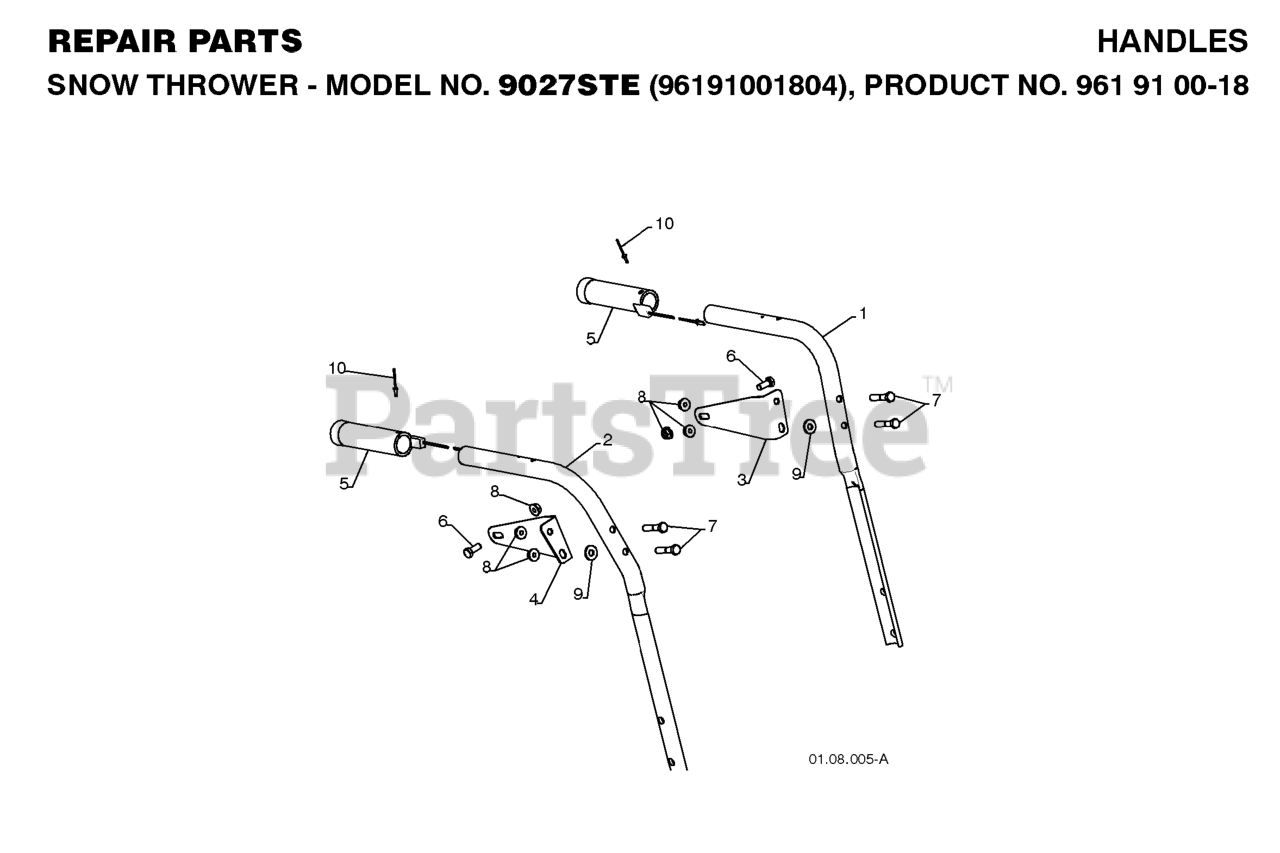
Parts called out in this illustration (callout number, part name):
1	TUBE.HANDLE.PLOW.LH.BLACK
2	TUBE.HANDLE.PLOW.RH.BLACK
3	BRKT.PANEL.LH.INT
4	BRKT.PANEL.RH.INT
5	GRIP.HANDLE.HEATED
6	BOLT.FIN.HEX.5/16-18X3/4
7	HEX BOLT
8	NUT.LOCK.5/16-18
9	WASHER.20X8.5
10	RIVET.POP.1/8X
